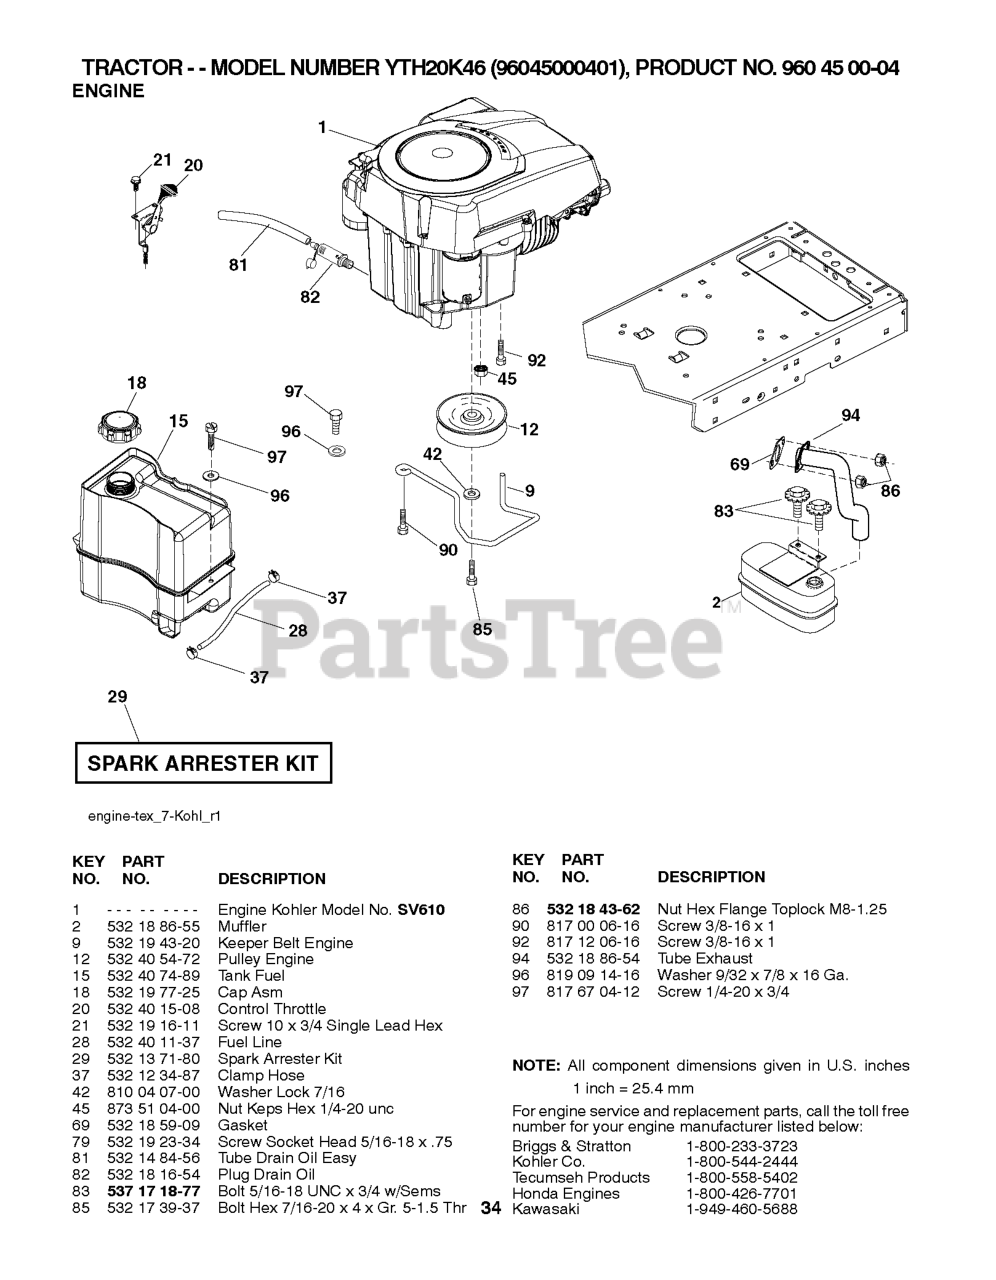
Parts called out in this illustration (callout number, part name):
2	MUFFLER.SINGLE.CYL.KOHL/B&S
9	KEEPER.BELT.ENGINE.4.2
12	RP_PULLEY ENGINE
15	TANK.ASM.FUEL.FR.2.5GA.
18	FUEL CAP
20	CONTROL.TH/CK.COBRA.KO
21	SCREW
28	LINE.FUEL.20"FRONT.EMI
29	KIT.SPARK ARRESTOR 794945 B&S
37	HOSE CLAMP
42	LOCKWASHER
45	NUT
69	GASKET.EXHAUST.KOHLER
79	SCREW.SOCKET HD.5/16-1
81	TUBE, DRAIN OIL ASM.
82	PLUG DRAIN OIL EASY
83	BOLT 5/1618UNC X 3/4 W/ SEMS
85	BOLT HEX 7/16-20X4-1/4"
86	NUT.HEX.FLANGE.TOPLOCK
90	SCREW 3/8-16X1
92	SCREW 3/8-16X1
94	RP.TUBE.EXHAUST.KOHL.COURAGE
97	SCREW HEXWSHR 1/4-20X3/4
